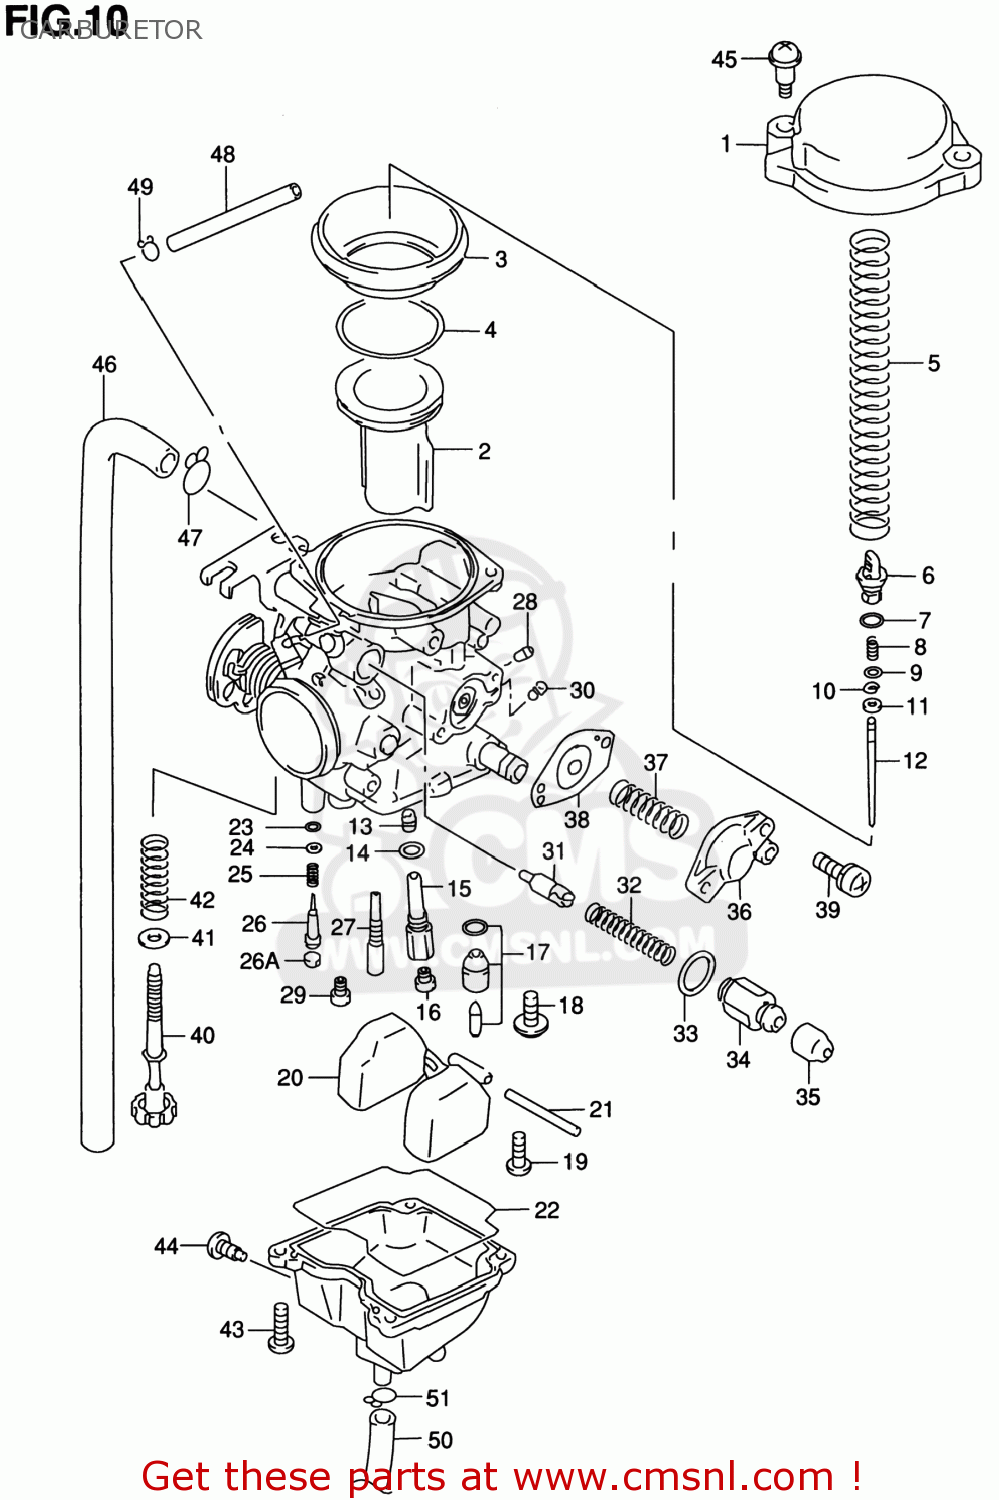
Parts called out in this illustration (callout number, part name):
1	COVER,DIAPHRAGM
2	VALVE,PISTON
3	DIAPHRAGM
4	RING
5	SPRING
6	HOLDER
7	O RING(D:1.9,ID:4.8)
8	SPRING
9	WASHER
10	E RING,MULTIPLE JET NOZZLE
11	RING
12	NEEDLE,JET
13	JET,NEEDLE(P-0M)
14	O RING
15	HOLDER,JET
16	JET,MAIN(120)
17	VALVE ASSY,NEEDLE
18	SCREW
19	SCREW
20	FLOAT ASSY
21	PIN,FLOAT
22	GASKET (NAS)
23	O RING,PILOT AIR SCREW
24	WASHER
25	SPRING,THROTTLE SCREW
26	ADJUSTER
26A	PLUG
27	JET,PILOT(17.5)
28	JET,MAIN(87.5)
29	JET,MAIN(52.5)
30	JET,PILOT AIR(120)
31	PLUNGER
32	SPRING
33	O RING
34	HOLDER,GUIDE
35	CAP
36	COVER ASSY
37	SPRING
38	DIAPHRAGM ASSY
39	SCREW
40	SCREW,ADJUST
41	PACKING (NAS)
42	SPRING
43	SCREW
44	SCREW,DRAIN
45	SCREW
46	HOSE
47	CLIP
48	HOSE
49	CLIP
50	HOSE
51	CLIP
